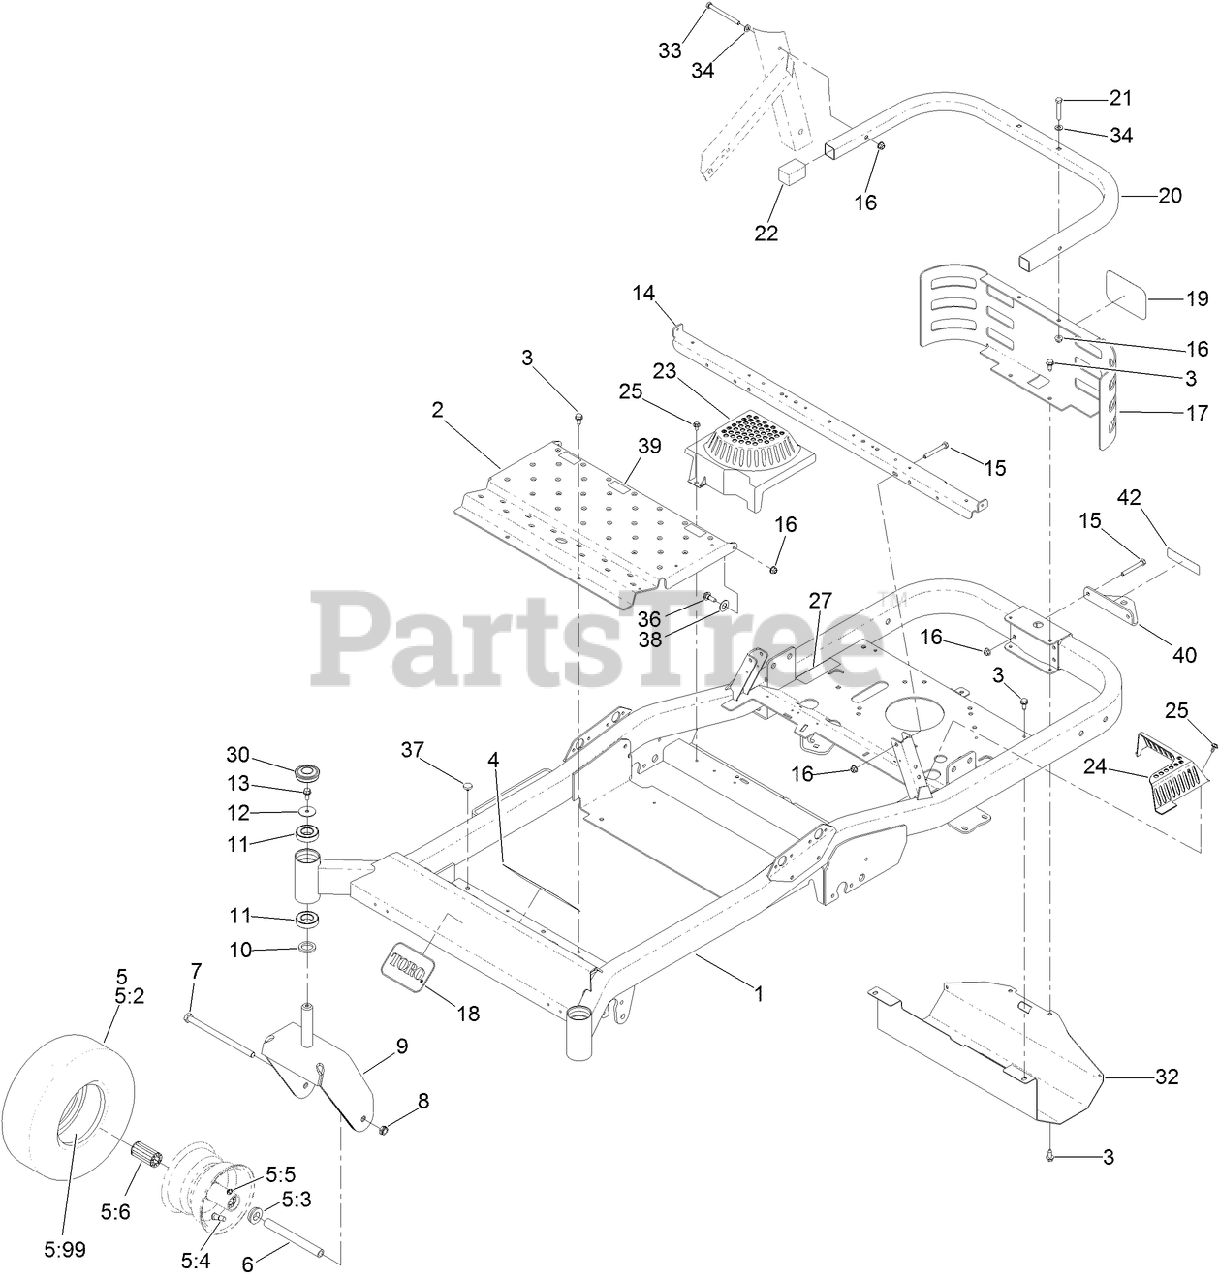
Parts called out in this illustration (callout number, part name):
1	FRAME ASM
2	PAN-FLOOR
3	SCREW-HWHTF
4	DECAL-DANGER
5	TIRE AND WHEEL ASM
5:3	BUSHING-FLANGE
5:4	VALVE
5:5	FITTING-ZERK
5:6	BEARING
5:99	TUBE-INNER
6	SPANNER-WHEEL, CASTER
7	SCREW-HH
8	NUT-HEX
9	CASTER FORK ASM
10	WASHER-THRUST
11	BEARING-BALL
12	WASHER-FLAT
13	SCREW-HHF
14	SUPPORT-SEAT
15	SCREW-HH
16	NUT-HF, NI
17	GUARD-REAR
18	DECAL
20	TUBE-GUARD
21	SCREW-HH
23	COVER-FAN, RH
24	COVER-FAN, LH
25	SCREW-HHFTF
27	DECAL-EMISSIONS
30	CAP-GREASE
32	SHIELD-HEAT
33	SCREW-HH
34	WASHER-PLAIN
36	SCREW-SHOULDER
37	BUMPER
38	WASHER-TEFLON
39	PAD-RUBBER
40	BRACKET-HITCH
